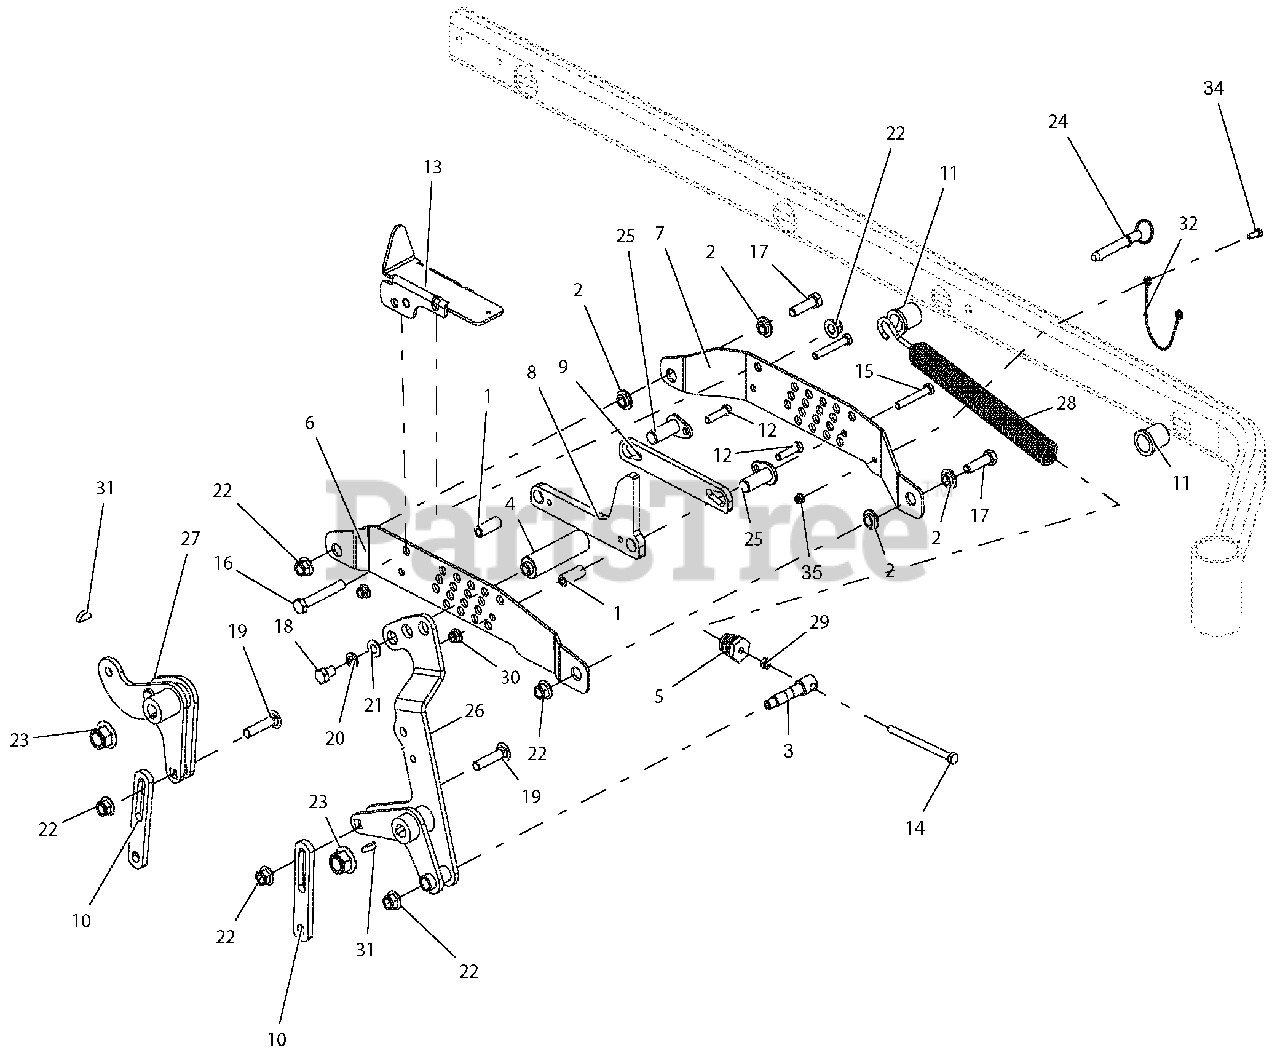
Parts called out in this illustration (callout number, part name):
1	SPACER, .375 X .625 X 1.54
2	BSHG, FLANGE .515X.750X.31X1.12
3	TRUNION, SPRG
4	PEDAL, LIFT
5	PLUG, SPRG
6	BRKT, RH INBOARD LIFT/CUT HEIGHT-BLACK
7	BRKT, RH INBOARD LIFT/CUT HEIGHT-BLACK
8	BRKT, HOC STOP-BLACK
9	BRKT, HOC STOP-BLACK
10	LINK, DECK LIFT - LONG
11	BSHG-FLG 1.00X1.25X1.5X1.5
12	BLT-HEX .38-16X1.50 GR5 YWZC EP30
13	WLDMT, MECHANICAL LOCK-UP-BLACK
14	BLT-HEX .38-16X5.00 GR5 YWZC
15	BLT-HEX .38-16X2.50 GR5 YWZC
16	BLT-HEX .50-13X3.25 GR5 YWZC
17	BLT-HEX .50-13X1.75 GR5 YWZC
18	BLT-HEX .50-13X.75 GR5 YWZC
19	BLT-RDHDSQNK .50-13X2.25 G5 Y
20	WSHR-LK .50X.125 REG YWZC
21	WSHR-FL-STL .505X1.00X.062 YWZC
22	NUT-LK-NYL-FLG .50-13 YWZC
23	NUT-LK-NYL-FLG .75-10 YWZC
24	PIN, .50 X 2.00 USABLE LG BALL
25	WLDMT, PIN
26	WLDMT, FRONT RH DECK LIFT ARM-BLACK
27	WLDMT, REAR RH DECK LIFT ARM-BLACK
28	SPRG, DECK LIFT
29	NUT, JAM .375-16 YWZC
30	NUT-LK-NYL-FLG .38-16 YWZC
31	KEY, WDRF .25 X 1.00 HRD #15
32	LANYARD, 12"
34	BLT-HEX .25-20X.75 GR5 YWZC
35	NUT-LK-NYL-FLG .25-20 YWZC
